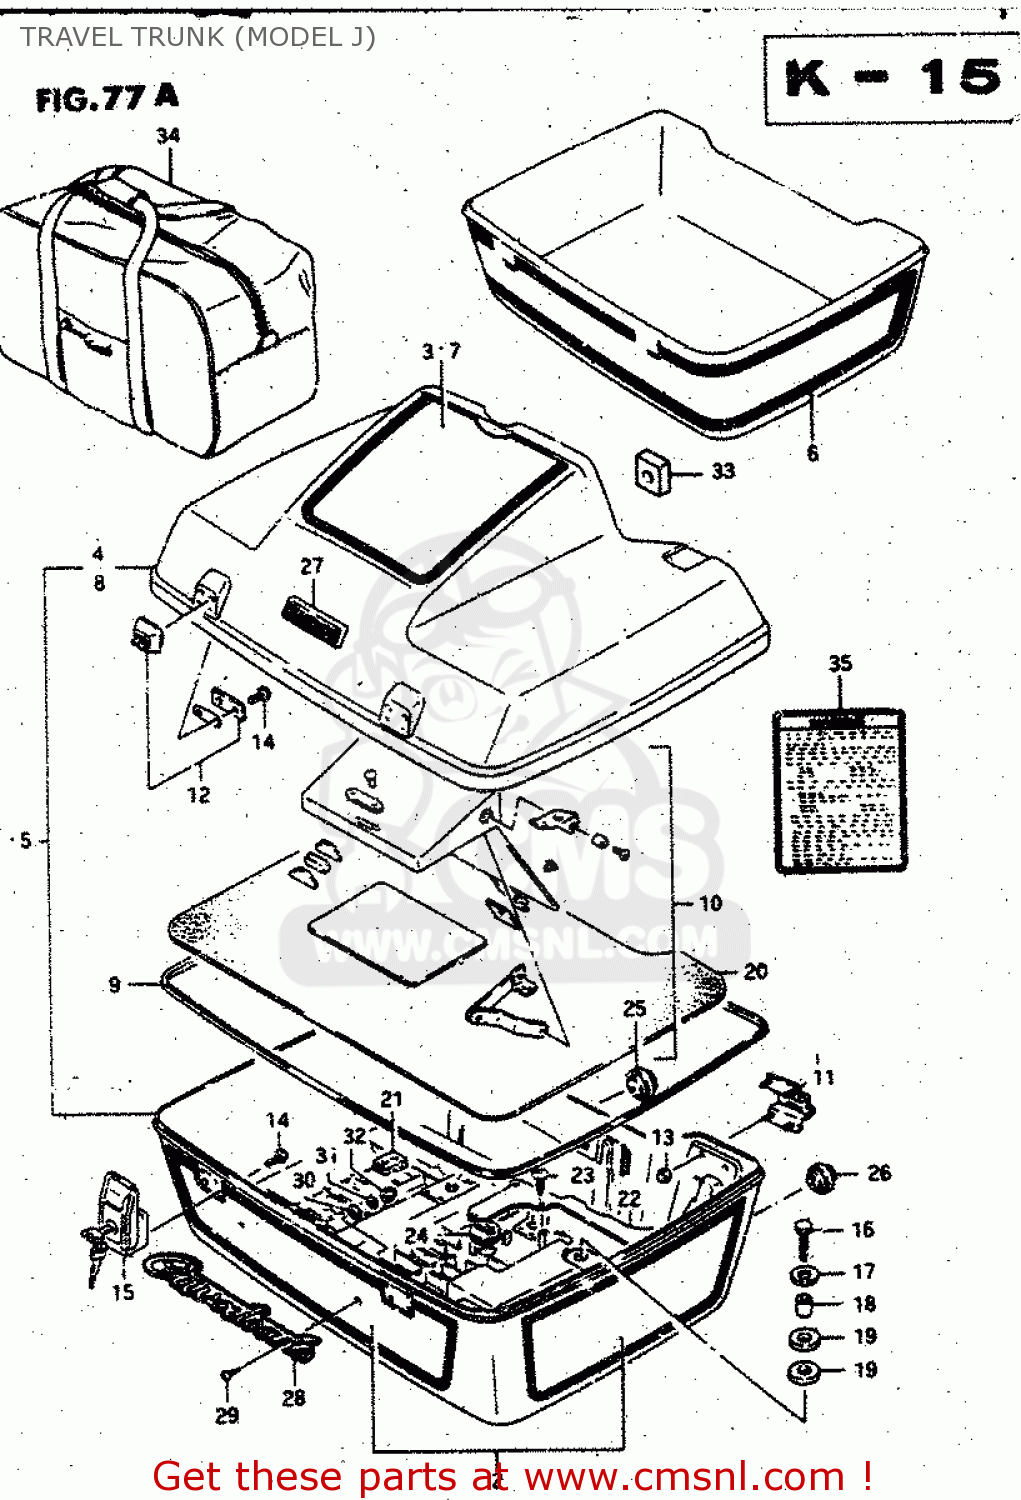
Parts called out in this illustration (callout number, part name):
1	TRUNK ASSEMBLY,TRAVEL
2	TAPE SET,TRAVEL TRUNK
3	TAPE SET,TRUNK LID STRIPE
4	LID,TRAVEL TRUNK
5	TRUNK ASSEMBLY,TRAVEL
6	TAPE SET,TRAVEL TRUNK
7	TAPE SET,TRUNK LID STRIPE
8	LID,TRAVEL TRUNK
9	SEAL,TRAVEL TRUNK LID
10	MIRROR,TRAVEL TRUNK
11	HINGE,TRAVEL TRUNK
12	PLATE,TRUNK LID LOCK
13	NUT
14	SCREW
15	LOCK ASSY, SIDE BAG
16	BOLT
17	WASHER
18	SPACER(6.3X9.3X16.5)
19	CUSHION
20	SEAT,TRAVEL TRUNK BODY
21	GROMMET
22	COVER, AIR HOSE
23	SCREW
24	GROMMET
25	GROMMET
26	GROMMET
27	EMBLEM,TRAVEL TRUNK,UPPER
28	EMBLEM,TRAVEL TRUNK,LOWER
29	SCREW
30	WASHER
31	WASHER
32	NUT
33	SEAL
34	LUGGAGE BAG,TRAVEL TRUNK
35	LABEL (WARNING TRAVEL T
